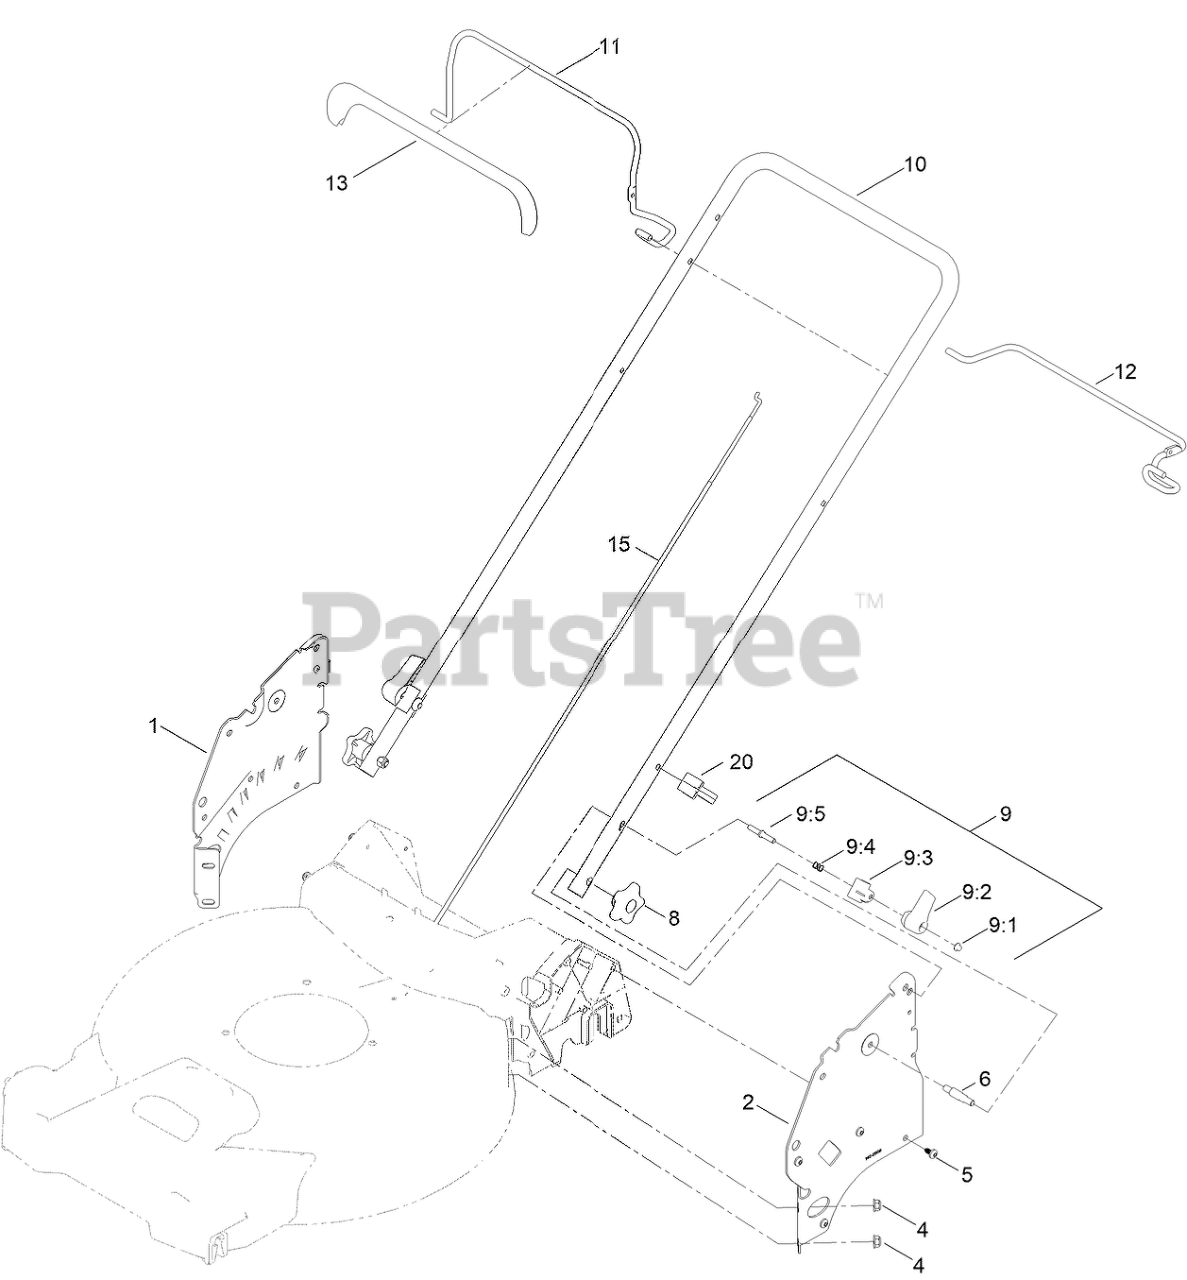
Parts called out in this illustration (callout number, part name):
1	PLATE-HANDLE, RH
2	PLATE-HANDLE, LH
4	NUT-HF
5	SCREW-PLASTIC,PH
6	BOLT-SHOULDER, HANDLE
8	KNOB-HANDLE
9	QUICK RELEASE ASM
9:1	NUT-PUSH
9:2	LEVER-RELEASE
9:3	ANCHOR-SPRING
9:4	SPRING-COMPRESSION
9:5	ROD-RELEASE
10	HANDLE-UPPER
11	BAIL-BRAKE
12	BAIL-TRACTION
13	COVER-BAIL
15	CABLE-TRACTION
20	GUIDE-CABLE
